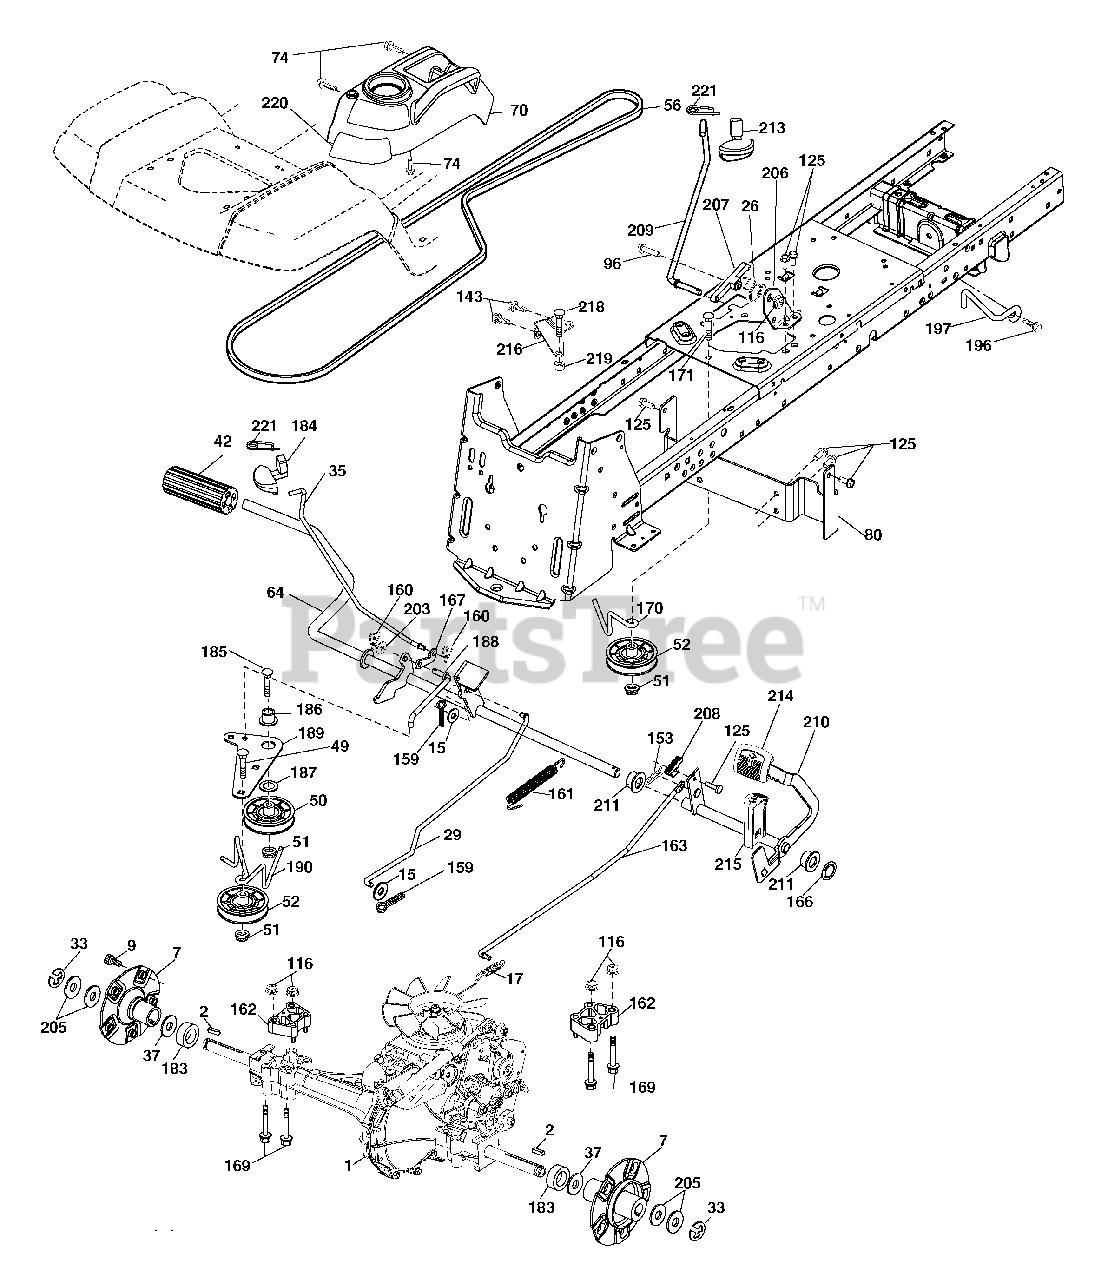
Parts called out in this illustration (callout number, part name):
2	Key 1/4 x 2.5
7	Hub Asm. Wheel
9	Bolt Hub Wheel
15	Washer 13/32 x 13/16 x 16 Ga.
17	Spring, Brake
26	Spring Return Cruise
29	Rod, Brake
35	Rod, Brake, Park
42	Cover, Foot Pedal
50	Pulley Idler Flat
51	Lock Nut 3/8-16
52	Idler V-Groove 910" Offset
56	V-Belt, Drive
64	Shaft Asm. Pedal Brake Control
70	Control Asm.
74	Screw 1/4 x 1/2
80	Bracket Strap Torque
96	Bolt Fin Hex 5/16-18 unc x 1.25
106	O-Ring Asm. Hydro
107	Line Fuel Hydro
108	Cap Asm. Vent
116	Nut Lock Hex Flange 5/16-18
121	Bracket Strap Torque
125	Screw 5/16-18 x 3/4
148	Screw 3/8-16 x 3/4
153	Retainer Spring
159	Pin Cotter 1/8 x 3/4
160	Retainer Clip
161	Spring, Return, Clutch
162	Spacer Transaxle
163	Rod Pedal Control
166	Nut Push .625
167	Latch Brake Parking
169	Bolt Hex Flghd 5/16-18 x 3.75
170	Keeper Belt Centerspan
183	Spacer Split
184	Handle Parking Brake
185	Bolt
186	Spacer Retainer
187	Washer
188	Link Clutch Ground Drive
189	Bellcrank Ground Drive
190	Keeper Bellcrank Ground Drive
196	Screw 3/8-16 x 1
197	Bracket Clutch Anti-Rotation
200	Nut Center Lock 5/16-18 unc
201	Bolt Shoulder 5/16-18 unc
203	Washer 11/32 x 11/16 x 16 Ga.
206	Bracket Mount Latch Cruise
207	Latch Control Cruise
208	Gear Sector Control Cruise
209	Rod Control Cruise
210	Rocker Asm. Pedal Control
211	Bearing Nylon
212	Screw 10-24 x 5/8 Wshd Qdrx
213	Knob Control Cruise
214	Pad Pedal Forward
215	Pad Pedal Reverse
216	Bracket Pulley Idler
217	Screw 5/16-18 x 1/2
218	Bolt Fin Hex 5/16-18 unc x 1-1/4
219	Spacer Fender
